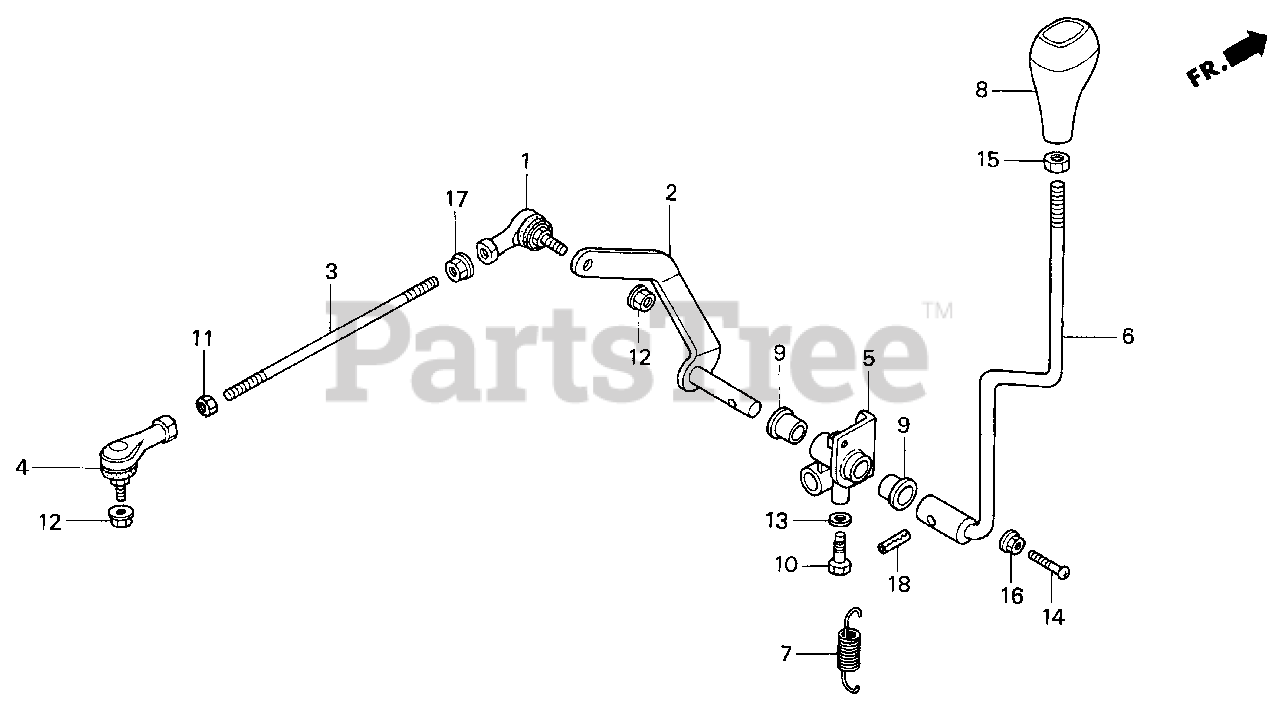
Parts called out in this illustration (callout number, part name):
1	JOINT, R. BALL
2	ARM, CHANGE
3	ROD, GEARSHIFT
4	JOINT, L. BALL
5	BOSS, CHANGE LEVER
6	LEVER, CHANGE
7	SPRING, BRAKE PEDAL
8	KNOB, SHIFT LEVER
9	BUSH (16X18X20)
10	BOLT, SPECIAL (8X24)
11	NUT, HEX. (8MM)
12	NUT, FLANGE (8MM)
13	WASHER, CONICAL SPRING (8MM)
14	SCREW, PAN (6X35)
15	NUT, HEX. (12MM)
16	NUT, FLANGE (6MM)
17	NUT, FLANGE (8MM)
18	PIN, SPRING (8X28)
